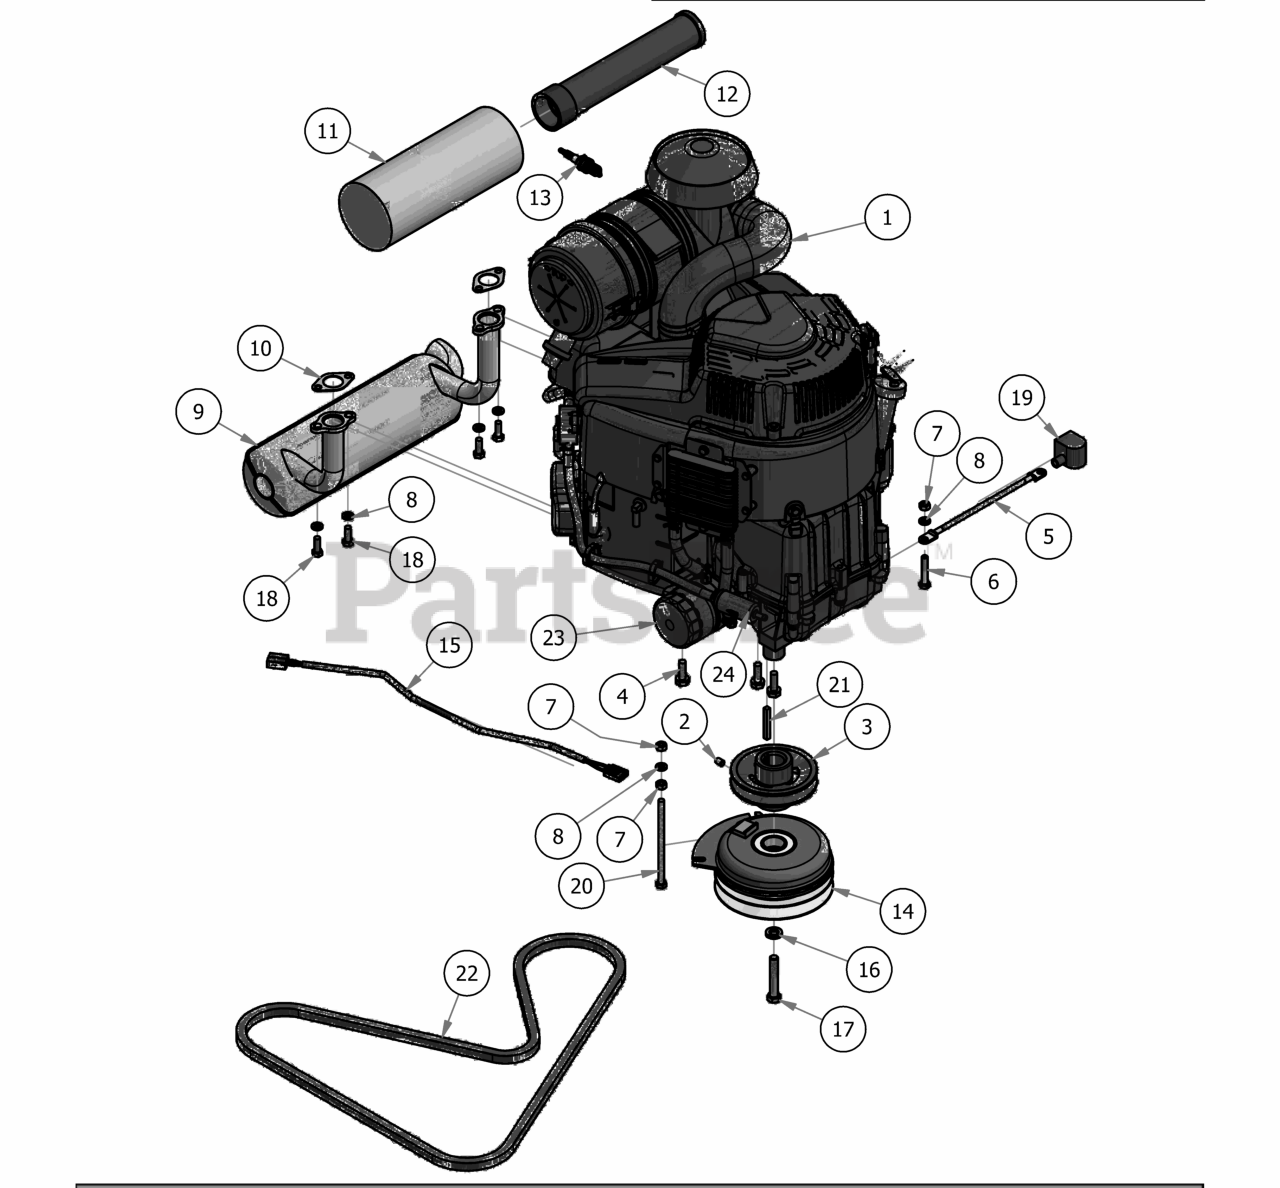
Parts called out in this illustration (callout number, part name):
1	810 Vanguard
2	3/8" Set Screw
3	4 3/4 Motor Pulley
4	3/8 x 1 1/8 bolt
5	Ground Cable
6	5/16" x 1 3/4" Hex Bolt
8	5/16" Lock Washer
9	Briggs Exhaust
10	Exhaust Gasket
11	Canister Air Filter- Outer
12	Canister Air Filter- Inner
13	Spark Plug
14	Clutch Assembly
15	Clutch Pigtail
16	7/16" Lock Washer
17	7/16" x 2 1/2" Hex Bolt
18	Torx Bolt-Exhaust
19	Black Boot For Ground Cable
20	5/16-18 x 5-1/2 GR 5 Hex Bolt
21	1/4 x 2 Square key Stock
23	Briggs Oil Filter
24	Universal Fuel Filter
